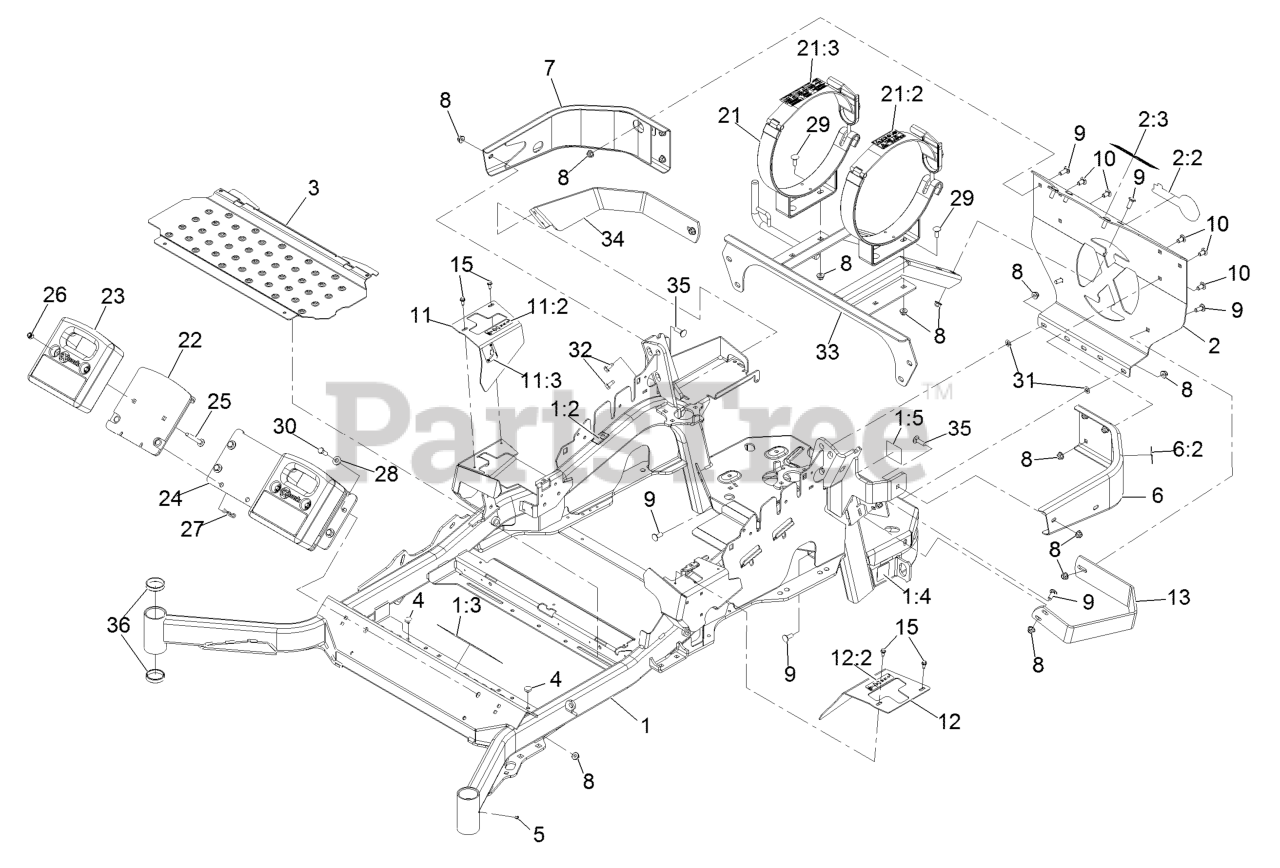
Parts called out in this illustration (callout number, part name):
1	Mainframe ASM
1:2	Decal-Warning
1:3	Decal-Danger
1:4	Decal-Hazard, Pinched Finger
1:5	Decal-Spark Arrester
2	Rear Guard-LP W/Decals
2:2	Decal-Exmark Logo
2:3	Decal-LPG Fuel Tank Replacement
6	LH Bumper ASM
6:2	Decal-Warning
7	Bumper-RH
8	Nut-Nyloc 3/8-16 Flg
9	Bolt-Carriage 3/8-16 X 1
10	Bolt-Carriage 3/8-16 X 3/4
11	RH Motion Control Cover ASM
11:2	Decal-Control, Motion
11:3	Decal-Park Brake, CE
12	LH Motion Control Cover ASM
12:2	Decal-Control, Motion
13	Guard-Muffler
15	Screw-HWH 1/4-20 X .62
21	Tank Bracket ASM (Set)
21:2	Decal-LPG Warning
21:3	Decal-LPG Tank Spec
22	Asm, Weight W/Decals
23	Weight,Cast 36Lb
24	Plate, Weight Mounting
25	Bolt-Carriage 3/8-16 X 3
26	Nut-Nyloc 3/8-16
27	Hairpin-Cotter
28	Washer-Spring Disc 3/8
29	Bolt-Carriage 3/8-16 X 1
30	Screw-HH 3/8-16 X 1
31	Nut-Push 3/8-16
32	Screw-HWH 5/16-18 X 3/4 Tf
33	Support-LPG Tank
34	Strap-Guard
35	Bolt-Carriage 3/8-16 X 1 1/4
36	Cup-Bearing Tapered Roller
